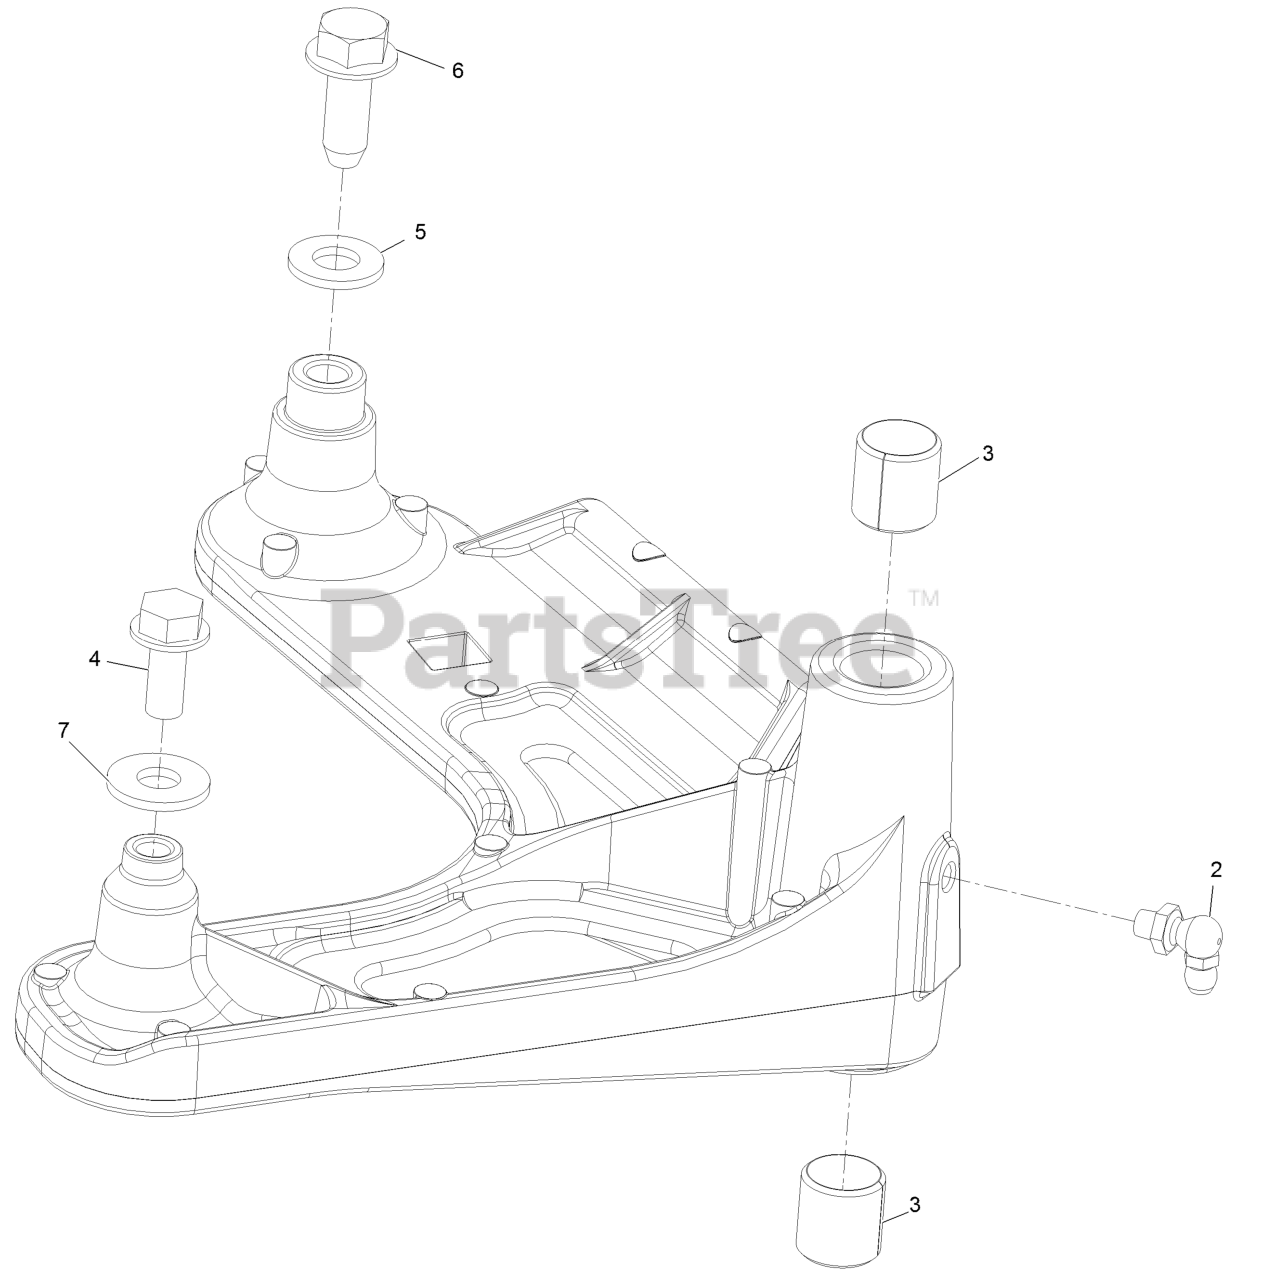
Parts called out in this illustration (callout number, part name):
2	Zerk-90deg 1/4-28
3	Sleeve-Bearing
4	Screw-HWH 5/16-18 X 3/4 Tf
5	Washer-3/8 SAE
6	Screw-Forming, Thread
7	Washer-5/16 Std
